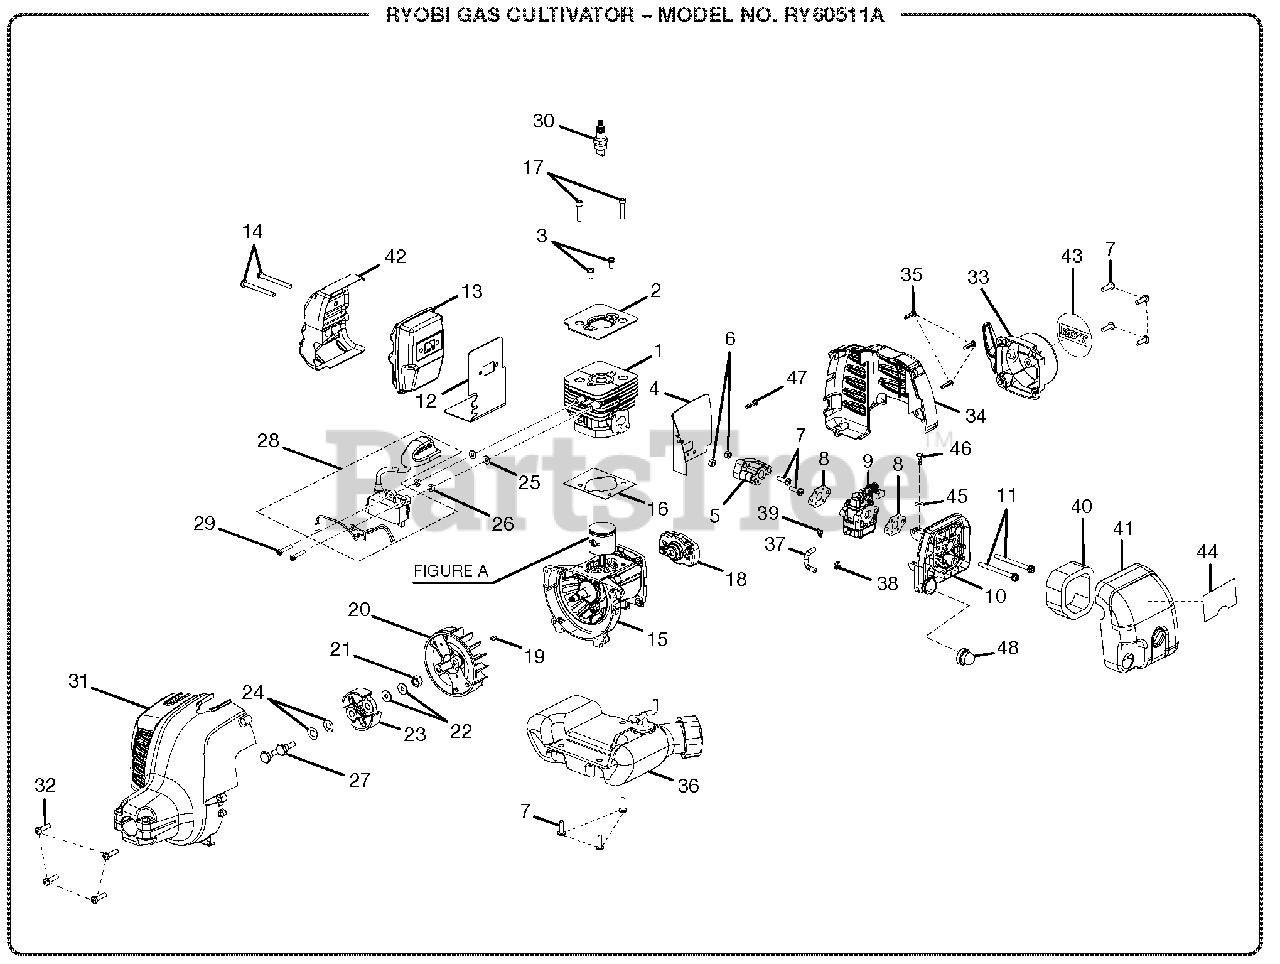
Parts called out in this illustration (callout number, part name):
1	25.4 CYLINDER
2	PLATE
3	SCREW (M5 x .8 mm PAN HD.)
5	INSULATOR
6	NUT (M5 x .8 mm)
7	SCREW (M.8 x 16 mm PAN HD.)
9	CARBURETOR ASSEMBLY
10	FILTER HOUSING ASSEMBLY
11	SCREW (M5 x .8 x 60 mm PAN HD.)
13	MUFFLER ASSEMBLY
14	SCREW (M5 x .8 x 50 mm PAN HD.)
15	CRANKCASE ASSEMBLY
17	SCREW (M5 x .8 x 22 mm)
18	PULLEY ASSEMBLY
19	WOODRUFF KEY
23	CLUTCH ASSEMBLY
24	WASHER, CURVED
27	SCREW (M6 x 1 x 14 mm PAN HD.)
28	COIL ASSEMBLY
29	SCREW (M4 x .7 x 22 mm PAN HD.)
30	SPARK PLUG
31	FRONT HOUSING ASSEMBLY
32	SCREW (M5 x .8 x 20 mm PAN HD.)
33	STARTER HOUSING ASSEMBLY
34	REAR ENGINE HOUSING
35	SCREW (M4 x 1.75 x 16 mm PAN HD.)
36	FUEL TANK
37	FUEL LINE
40	AIR FILTER
41	OUTER COVER ASSEMBLY
42	HEAT SHIELD
43	LOGO LABEL
44	PRIMER LABEL
46	SCREW (M4 x 16 mm TORX PAN HD.)
47	SCREW (M4 x 16 mm PAN HD.)
48	PRIMER
